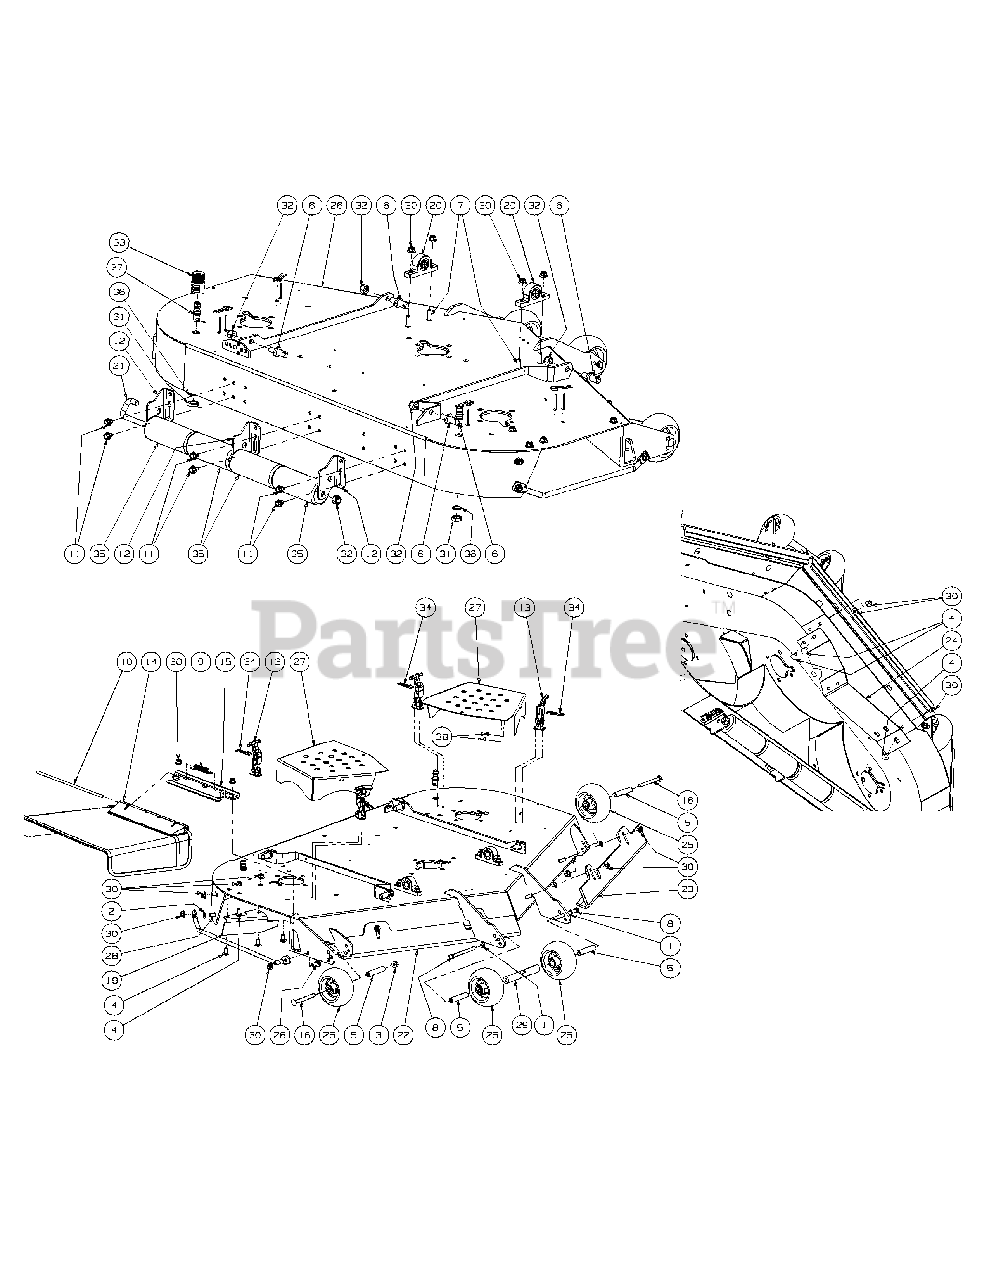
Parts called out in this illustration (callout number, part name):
1	Lock Washer, 3/8
2	Flat Washer, 3/8
3	Hex Nut, 3/8-16 Flange Lock
4	Carriage Bolt, 3/8-16 x .75 Lg.
5	Wheel Spacer
6	Pin, 5/8 Dia. x 1.2 Lg.
7	Carriage Screw, 3/8-16 x 1.25
8	Hex Cap Screw, 3/8-16 x 4.50
9	Spring Torsion, 0.4 ID x 2.16 LG
10	Defllector Chute Rod
11	Hex Index Washer Screw, 3/8-16, .5
13	T-Handle Draw Latch
14	Deflector Chute
15	Deflector Chute Bracket
16	Carriage Bolt, 3/8-16 x 4.00
17	Push Retainer
18	Finger Guard
20	Pillow Block
21	J-Hook w/ Threaded Roller
22	Right Hand Front Adjustment Skirt
23	Left Hand Front Adjustment Skirt
24	Baffle, 54" Adjustment
25	Complete Wheel, 5.00 Dia.
26	54" Deck Assembly
27	Deck Belt Cover
28	Carriage Bolt, 3/8-16 x 1
29	Ball Wheel Mounting Shaft
30	Lock Nut, Nylon Insert, 3/8-16
31	Hex Nut, M16-1.5
32	Lock Nut, Nylon Insert, 1/2-13
33	Water Nozzle Adaptor
34	Phillips Head Screw, 10-32
35	Front Roller
36	Lock Washer, 17 x 23.8 x 1.95
37	Deck Water Nozzle
38	Lock Nut, Nylon Insert, 10-32
